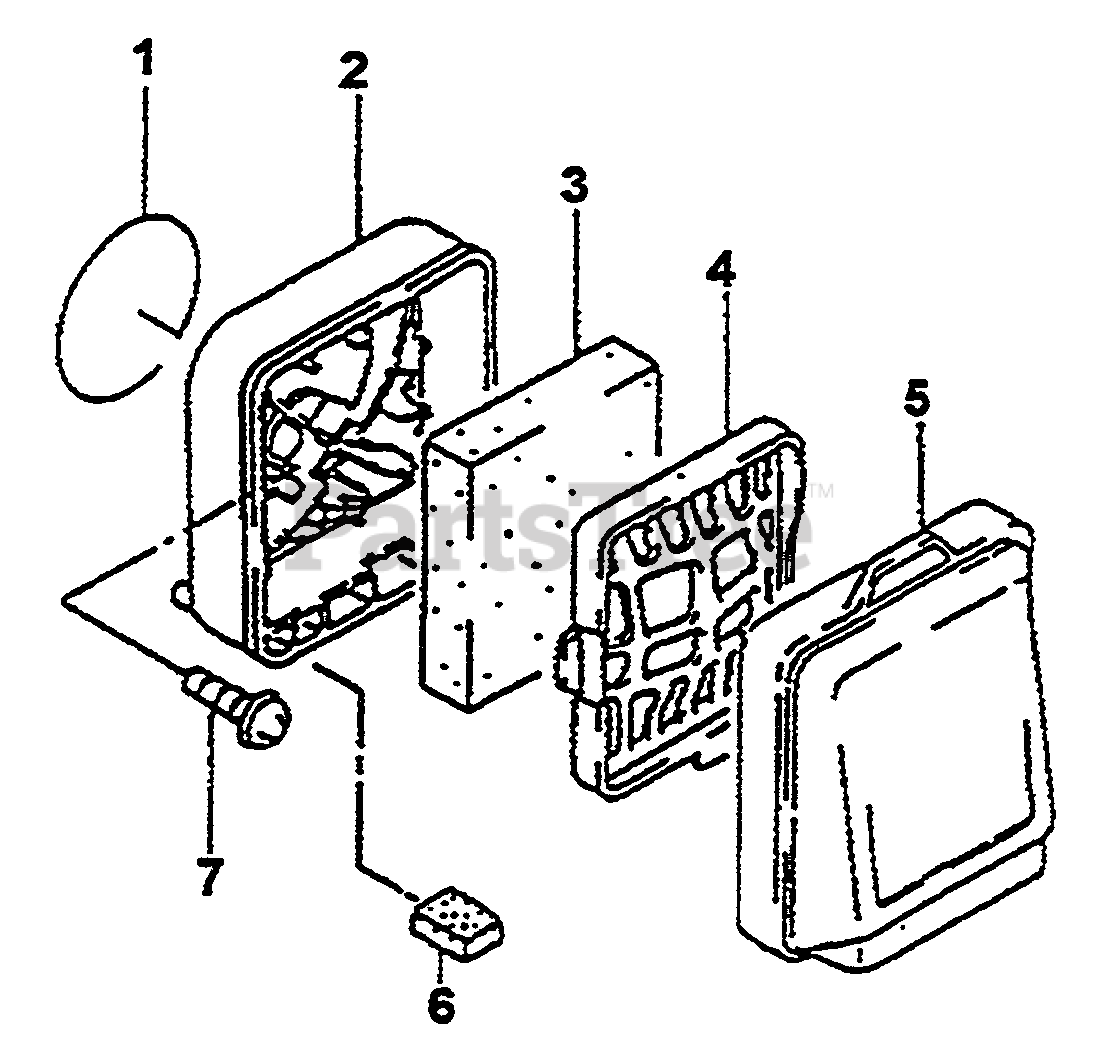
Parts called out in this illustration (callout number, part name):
3	ELEMENT
4	GRATE
6	ELEMENT
